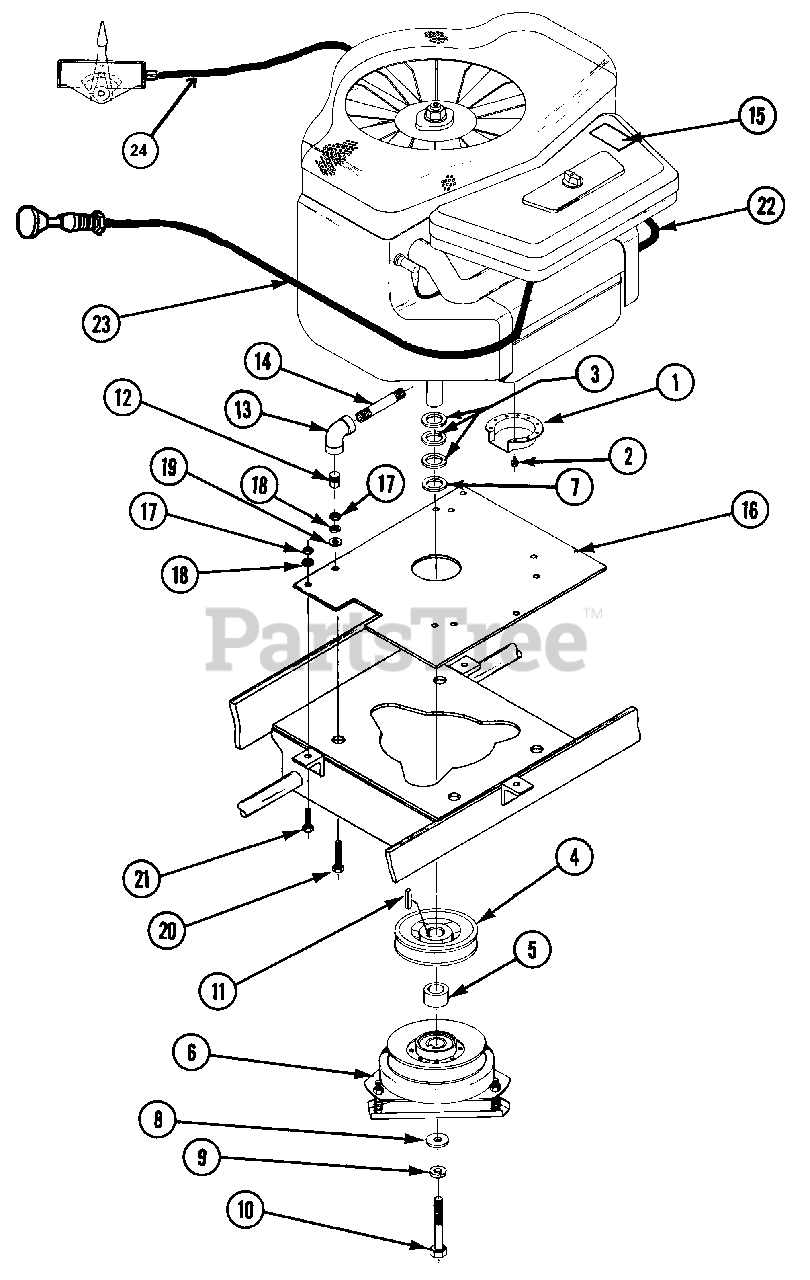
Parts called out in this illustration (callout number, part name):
1	SIDEOUT DEFLECTOR
2	SCREW FOR SIDEOUT DEFLECTOR
3	WASHER, 1-1/2 OD X 1 ID X 1/8 THK
4	PULLEY, BK50-1, 4" A PITCH
5	SPACER, PULLEY/ELECTRIC CLUTCH
6	CLUTCH, ELECTRIC, #5210-17 CU
7	WASHER, 1-1/2 OD X 1 ID X 1/16 THK
8	WASHER, 15/32" ID
9	LOCKWASHER, 7/16 STD, SPLIT SPRING
10	CAPSCREW, HEX, 7/16-20 X 3, GRADE 5
11	SQUARE KEYS 1/4" X 1"
12	3/8 PIPE PLUG
13	ELBOW, 3/8 X 90 DEG, SCH. 40, BLACK
14	NIPPLE, 3/8 X 3, SCH. 40, BLACK
15	DECAL "PERIODICALLY CLEAN DEBRIS"
16	MOTOR MOUNTING PLATE
17	NUT, 5/16-24 UNF, GRADE 5
18	LOCKWASHER, 5/16 HEAVY SPRING
19	WASHER, FLAT, STD, STEEL 5/16"
20	CAPSCREW, HEX, 5/16-24 X 1-1/2, GRADE 5
21	CAPSCREW, HEX, 5/16-24 X 1, GRADE 5
22	THROTTLE CABLE
23	CHOKE CABLE
